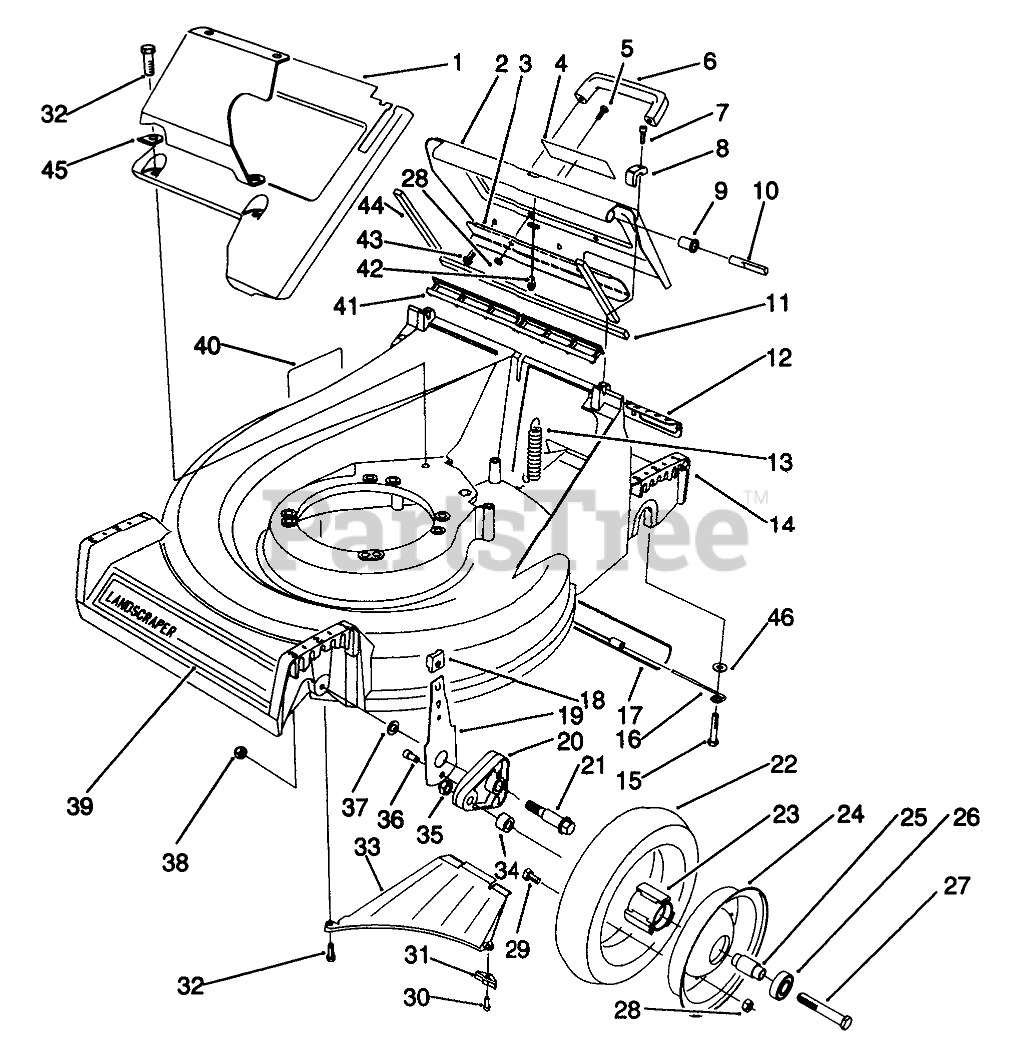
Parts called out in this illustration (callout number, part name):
1	PaneI-Screen
2	Door-Discharge (Incl. Ref. #4, 11 & 44)
3	DOOR - BRACE
4	DECAL - WARNING
5	SCREW-HH
6	HANDLE-DOOR
7	SCREW-HSH
8	HINGE CLAMP
9	DOOR BUSHING
10	HINGE PIN
11	DOOR END SEAL
12	ACCESS COVER
13	EXTENSION-SPRING
14	Housing-Deck (Incl. Ref. #39 & 40)
15	SCREW-SHOULDER
16	SHIELD HANGER
17	TRAILING SHIELD
18	KNOB-ARM
19	FRONT SPRING ARM ASM
20	ARM-PIVOT, FRONT
21	BOLT-SHOULDER
23	HUB-BEARING
24	Wheel-Half
25	SPACER-BEARING
26	BEARING-WHEEL
27	SCREW-HH
28	NUT-LOCK, NI
29	SCREW-HH
30	SCREW-HWHTF
31	Bracket-Discharge
32	SCREW-HWHTF
33	Ramp Discharge
34	SPACER-WHEEL
35	NUT-LOCK, NI
36	SCREW-HSH, THREAD FORMING
37	WASHER
38	Nut
39	DECAL - LANDSCAPER
40	DECAL-DANGER
41	DOOR SEAL
42	DOOR CABLE
43	SCREW-HWH
44	DOOR SIDE SEAL
45	BASE TANK
46	WASHER-PLAIN
